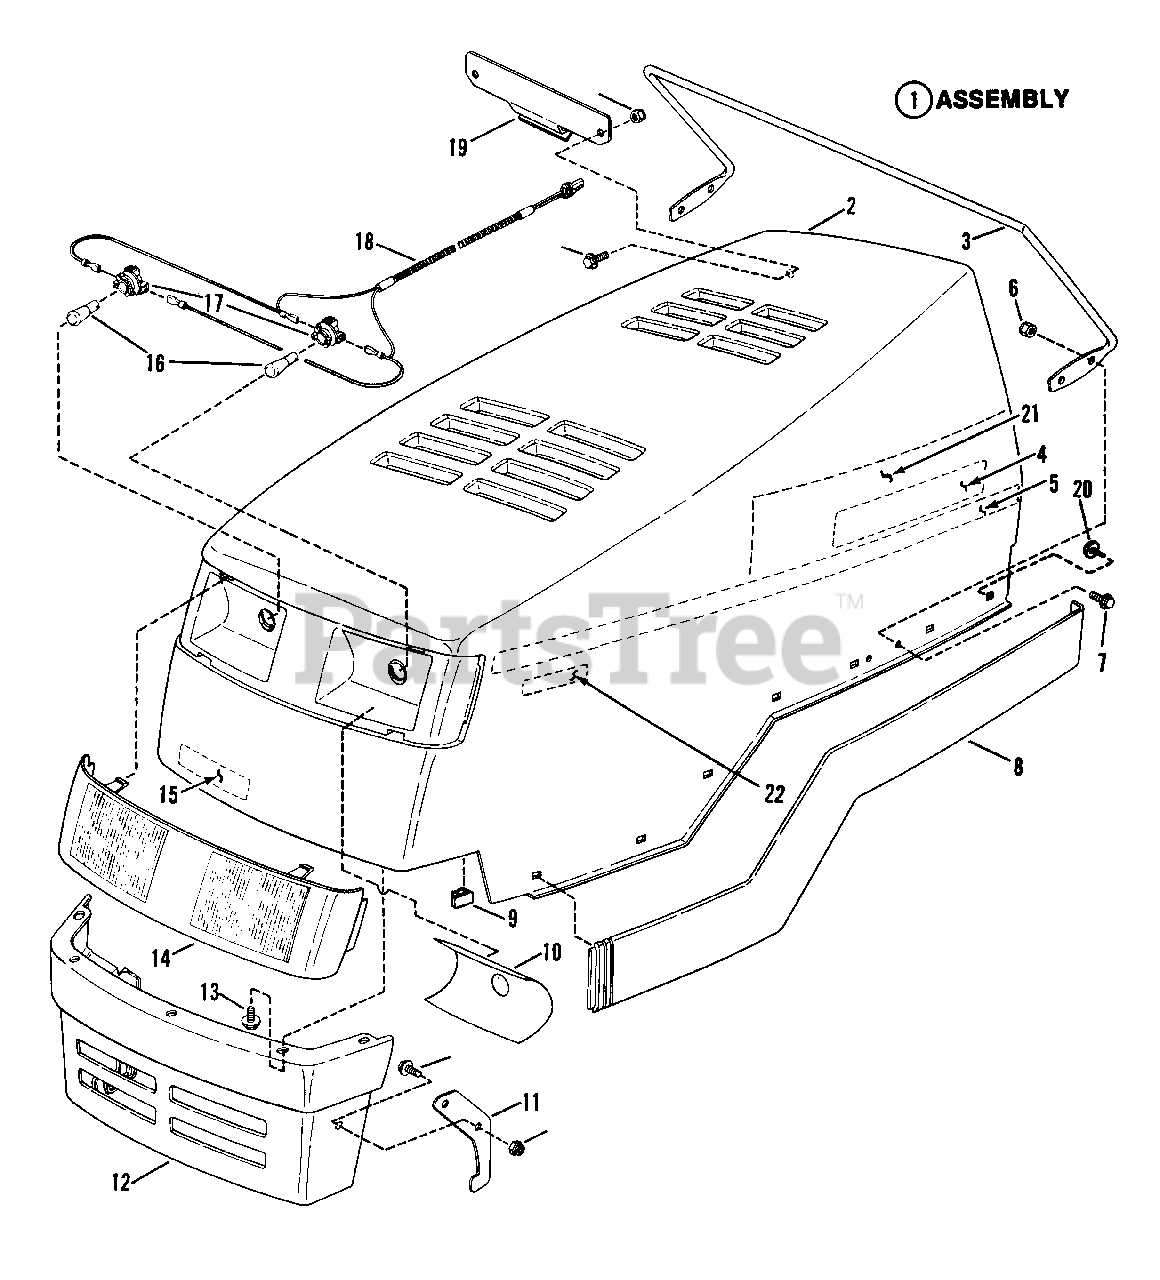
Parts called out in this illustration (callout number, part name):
1	KIT, Hood Assembly, Sloped Mozart
2	HOOD (No longer available)
3	ROD, Hood Latch
4	LOGO-SNAPPER, Molded
5	DECAL, Stripe (R.H.)
5	DECAL, Stripe (L.H. Shown)
6	LOCKNUT, 1/4-20 Hex
7	SCREW, 1/4-20 x 5/8 Torx, Truss Head
8	BUMPER (R.H.)(No longer available)
8	BUMPER (L.H. Shown)(No longer available)
9	CLIP, Wiring Harness
10	DECAL, Reflect (R.H.)
10	DECAL, Reflect (L.H. Shown)
11	BRACKET, Latch Hook
12	BUMPER, Front (No longer available)
13	SCREW, #12 x 1/2"
14	LENS, Clear Bezel
15	LOGO-SNAPPER, Molded
16	BULB, Headlights, 1156
17	SOCKET, Headlight Bulb
18	HARNESS, Headlight Wiring
19	CLIP, Spring Latch
20	FASTENER, Ratchet
21	HEAT SHIELD, Hood
22	DECAL, Model LT14H33
22	DECAL, Model LT14H41
